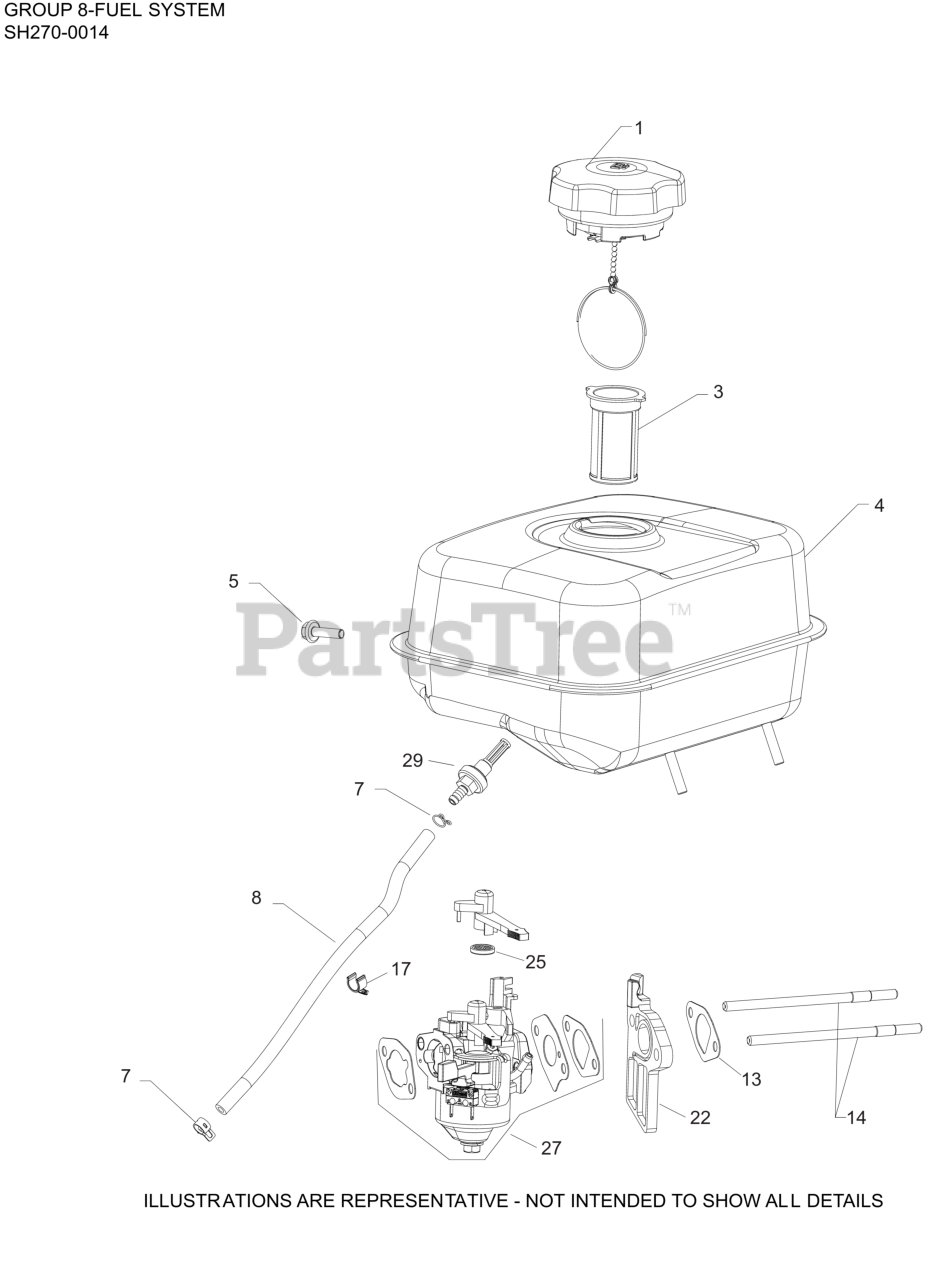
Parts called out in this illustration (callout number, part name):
1	CAP, FUEL ASSEMBLY
3	FILTER, FUEL TANK
4	KIT, FUEL TANK
5	SCREW, HEX SOCKET HEAD CAP
7	CLAMP, FUEL LINE
8	LINE, FUEL (10"-CUT TO LENGTH)
13	KIT, INTAKE GASKET
14	STUD, CARBURETOR
17	CLIP, FUEL HOSE
22	INSULATOR, CARBURETOR
25	SEAL, INLET VALVE
27	KIT,CARB (HUAYI)
29	FITTING, FUEL ASSY
NI	TOOL, SPARK PLUG WRENCH ASSY
NI	KIT, CARBURETOR REPAIR (HUAYI)
NI	CLIP, FUEL HOSE
NI	KIT, HIGH ALT (4000-8000 FT)
NI	KIT, HIGH ALT (8,000+ FT)
